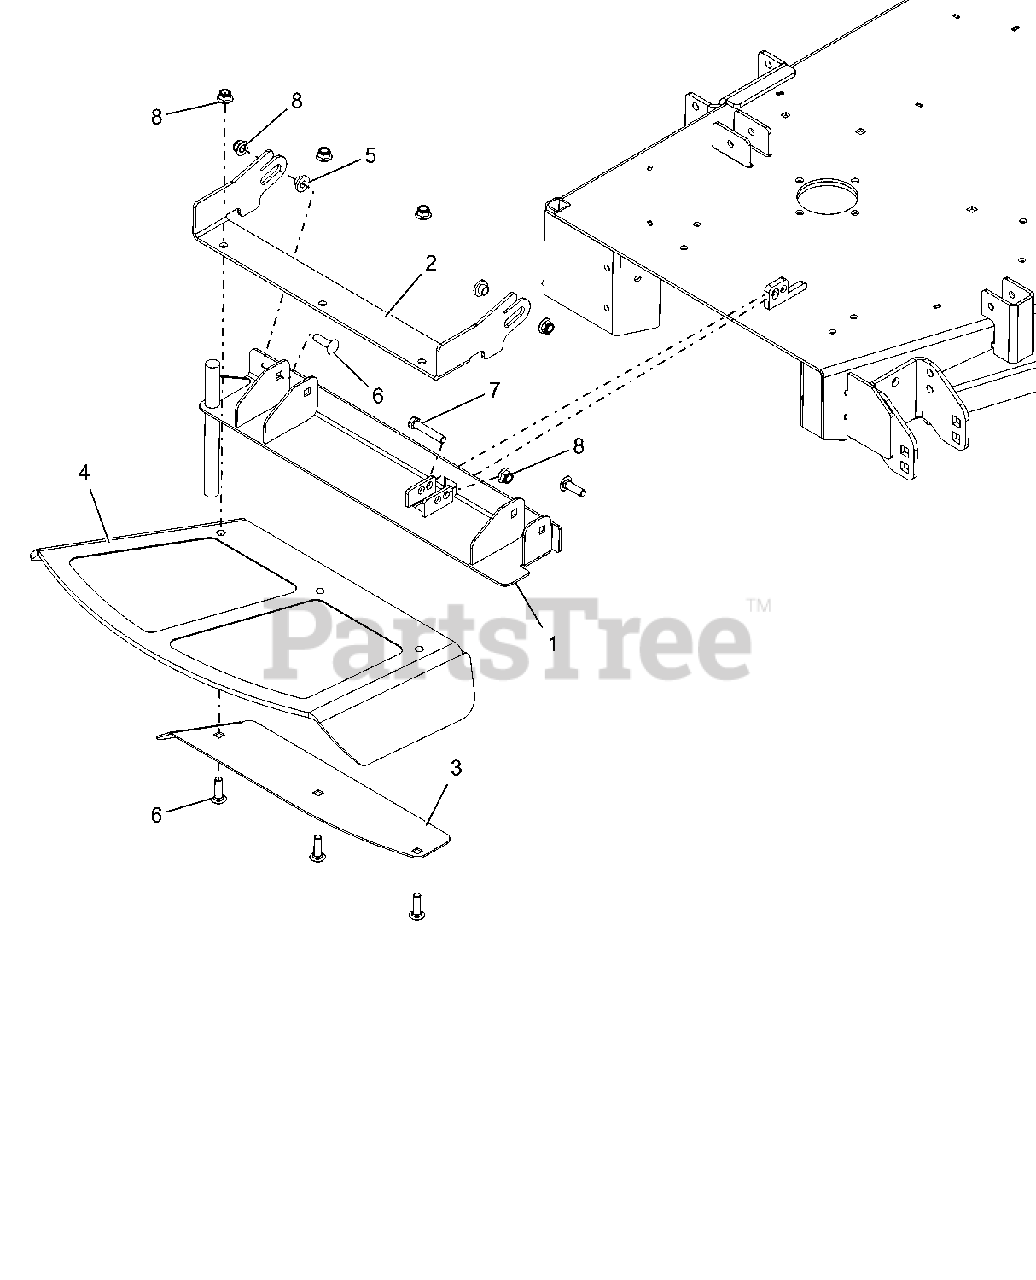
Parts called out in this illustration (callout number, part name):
1	48-60 DISCH CHT MTG WMT W/SAFE
2	48-60" CHUTE MTG BRKT - RED
3	48-60 DISCH CHUTE CLMP PLT-RED
4	CHUTE,48-60" FRMD RUBBER DISCH
5	BSHG-FLG .385X.500X.875X.406
6	@BLT-RHDSSQNK .38-16X1.25 G5YZ
7	@BLT-HEX .38-16X2.00 GR5 YWZC
8	@NUT-LK-NYL-FLG .38-16 YWZC
